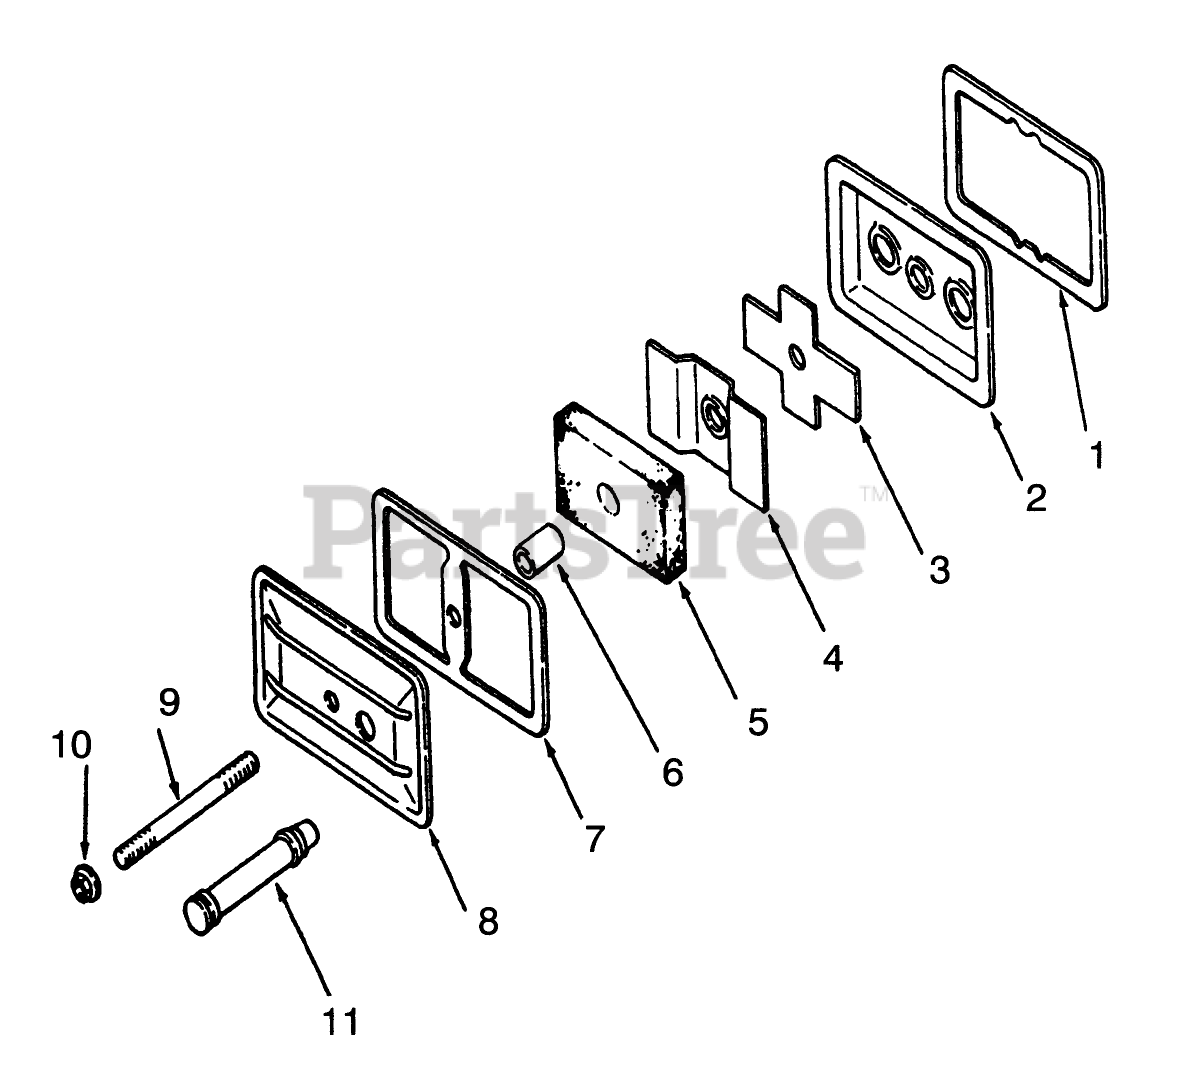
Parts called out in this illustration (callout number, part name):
1	KOHLER 235048
2	KOHLER 235631
3	KOHLER 235047
4	KOHLER 270146
5	KOHLER 47-050-01
6	KOHLER 231032
7	KOHLER 275144
8	KOHLER 47-096-01
9	KOHLER 275220
10	KOHLER X-799-1
11	KOHLER 47-326-03
